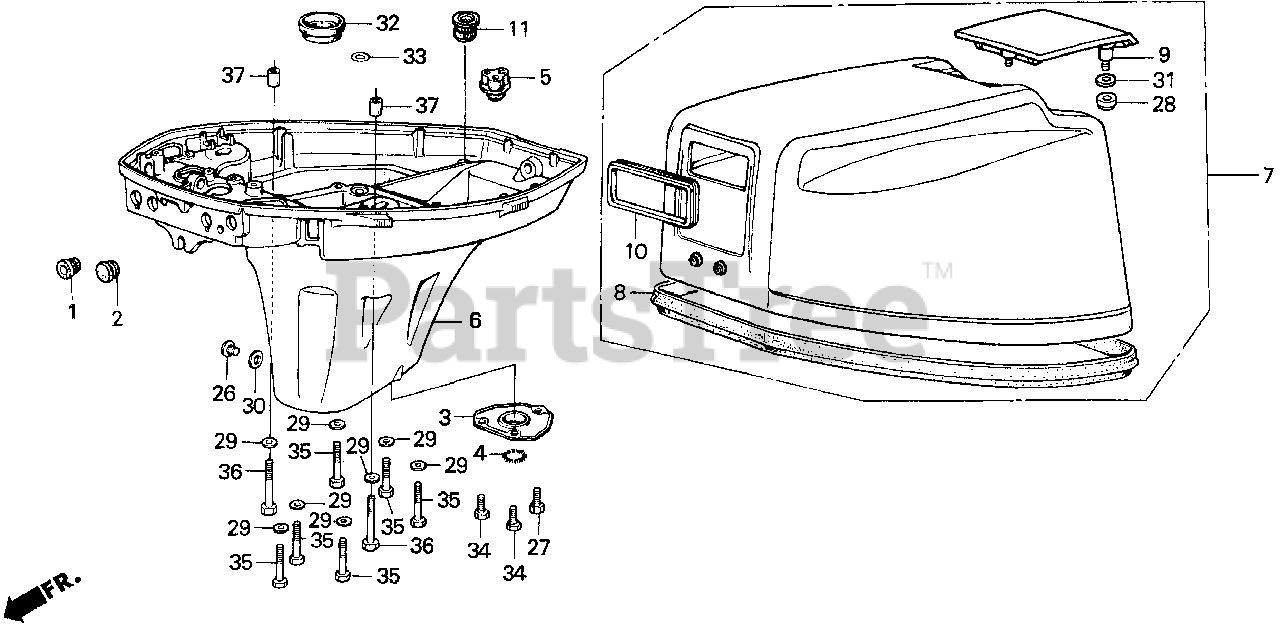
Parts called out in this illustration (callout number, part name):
1	GROMMET A, WIRE
2	GROMMET C, OIL CASE
3	PLATE, EX.
4	BAND, EX. SEAL
5	MANIFOLD, TUBE
6	CASE, OIL *NH282MU* (OYSTER SILVER METALLIC-U)
7	COVER, ENGINE *NH282MU* (OYSTER SILVER METALLIC-U)
8	SEAL, ENGINE COVER
9	HANDLE, TILT
10	SEAL, RECOIL
11	GROMMET, WATER CHECK
26	BOLT, OIL CHECK (8X8)
27	BOLT, HEX. (6X12)
29	WASHER, PLAIN (6MM)
30	WASHER, NYLON (8MM)
31	WASHER (6MM)
32	SEAL, COUPLING (25X40X22)
33	O-RING (9.8X1.9)
34	BOLT, HEX. (6X12)
35	BOLT, HEX. (6X32)
36	BOLT, HEX. (6X40)
37	PIN A, DOWEL (8X14)
